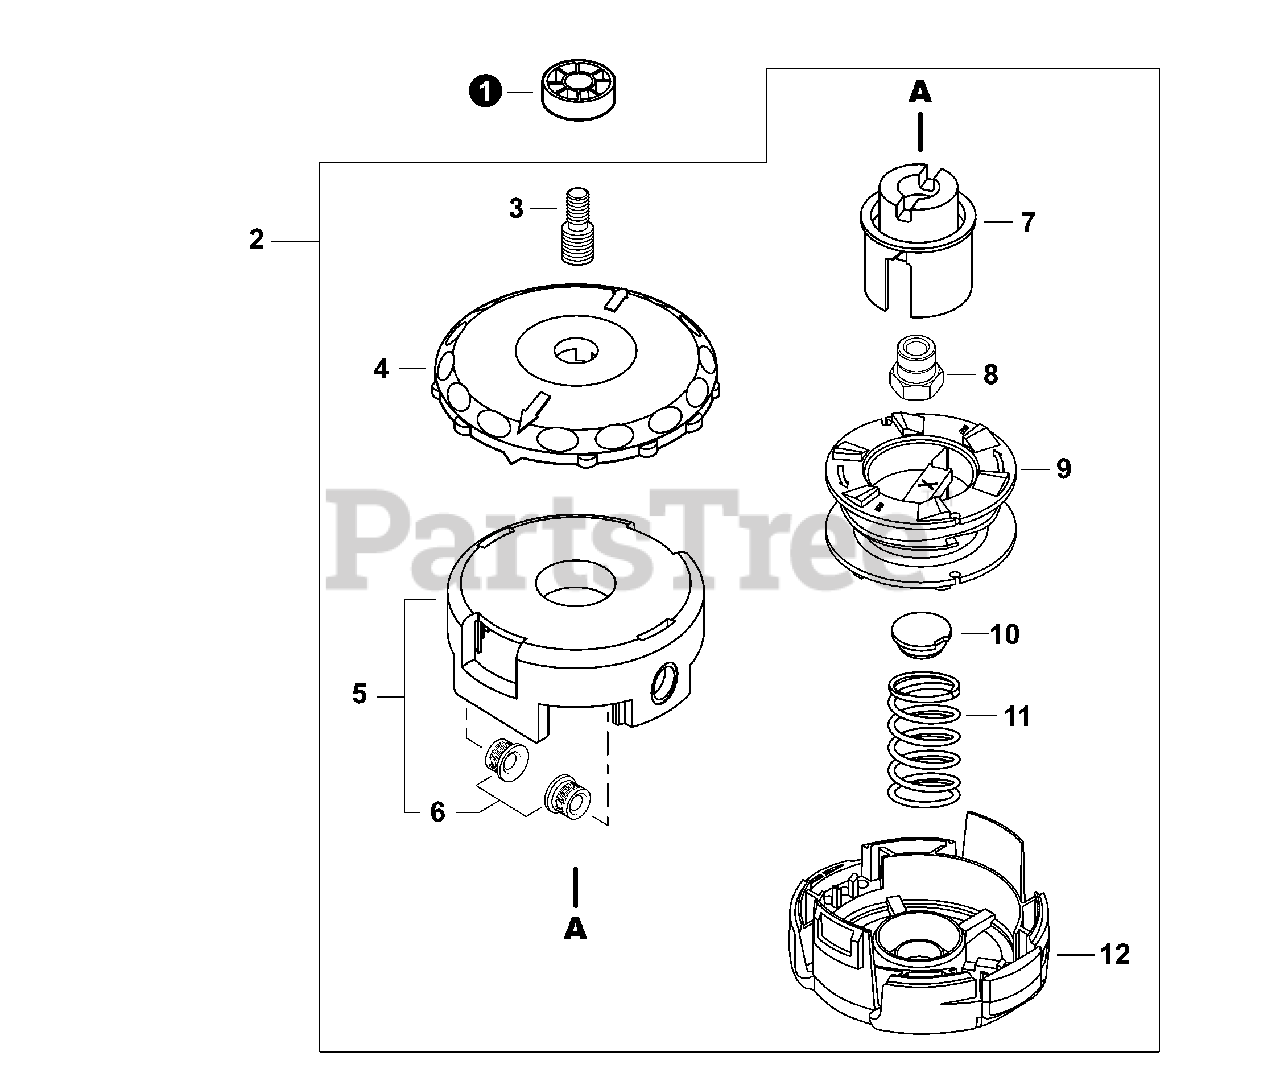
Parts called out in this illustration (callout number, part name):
1	SPACER, BLACK
2	TRIMMER HEAD, SPEED-FEED 400
3	BOLT, STUD M7 x 1.00 /M10 x 1.25 LH GOLD
5	HOUSING ASSY, SPOOL
7	HUB (LH) BLACK
8	BUSHING M10×1.25 LH GOLD
10	CAP, SPRING
11	SPRING, GOLD
12	COVER, SPOOL
